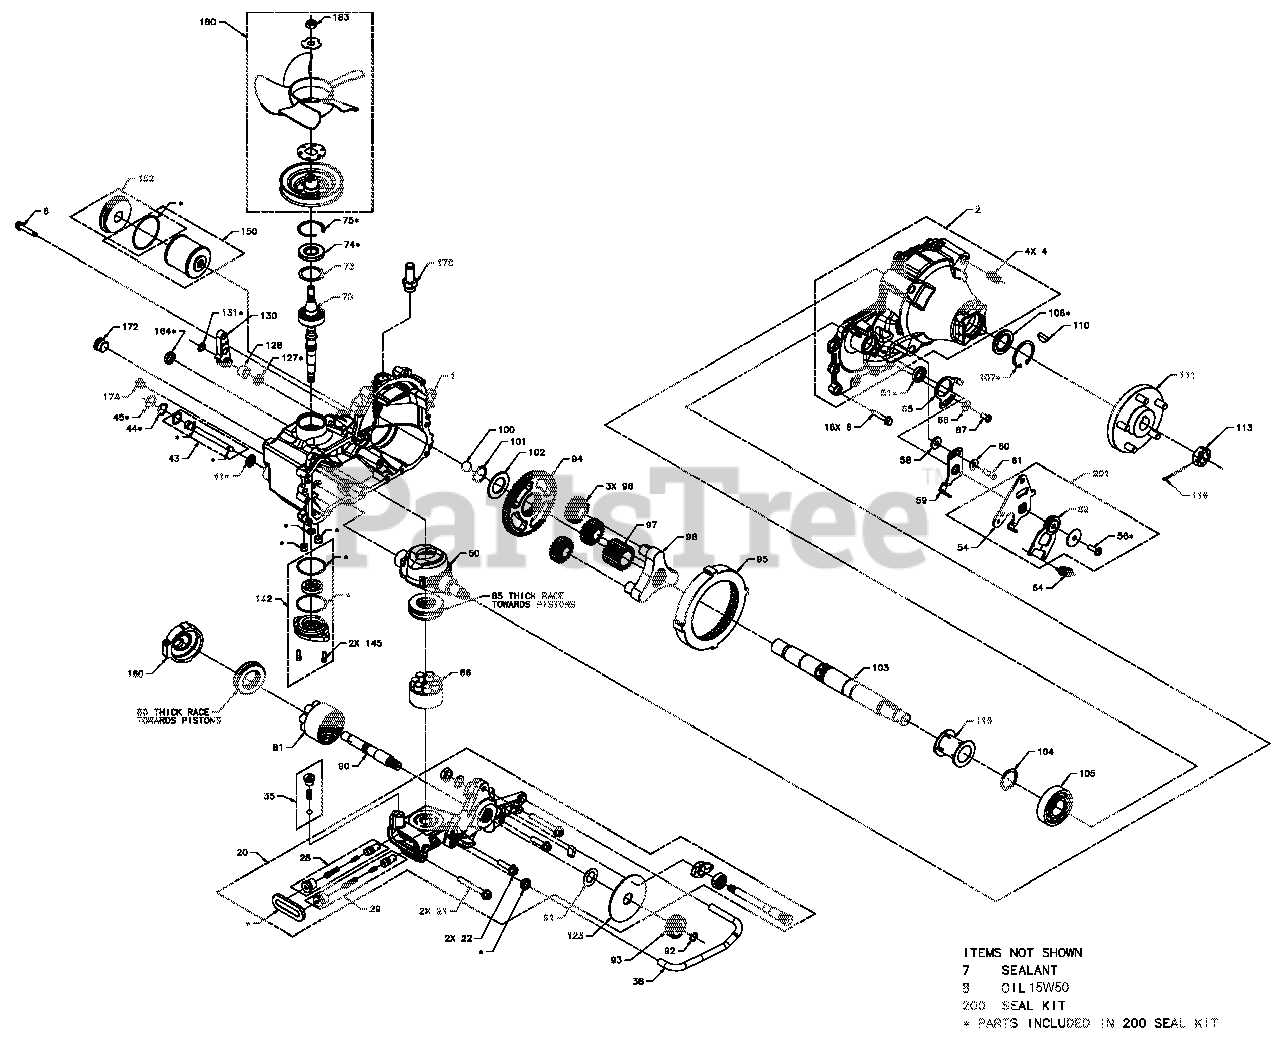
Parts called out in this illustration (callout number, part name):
7	Tube, Sealant
8	Synthetic Oil, 15W50
20	Kit, Center Section LH
28	Kit, Shock Valve
29	Kit, Shock Valve
35	Kit, Charge Relief
56	TWHCS, 5/16-24 x .875
58	Spacer, .320 x 1.005 x .179
59	Arm, Neutral LH
60	Washer, .34 x .88 x .06
61	SHCS 5/16-24 x .875
64	RTN SPRING HG 51605
66	Washer, .34 x .88 x .06
70	Input Shaft, HG 71941
81	Kit, Cylinder Block 21cc
92	Ring, Retaining
100	Ball, Thrust, .75
103	Shaft, Axle
105	Bearing, Ball 35 x 80 x 21
106	Seal, LIP 1.375 x 2.062 x 0.250
107	Ring, Retaining Internal
110	Key, Shaft Axle
111	Kit, Hub 5-Bolt
113	Nut, Hex 1-20 Slotted
116	Pin, Cotter, 9/64 x 2 Extended Prong
130	Brake Arm, HG 53018
142	Kit, Charge Cover
150	Filter, Hydraulic Oil w/O-Ring
152	Kit, Filter Plug
180	Kit, Pulley/Fan HG 71906
183	Nut, Hex 1/2-20 w/Patch
200	Kit, Seal HG 71945
